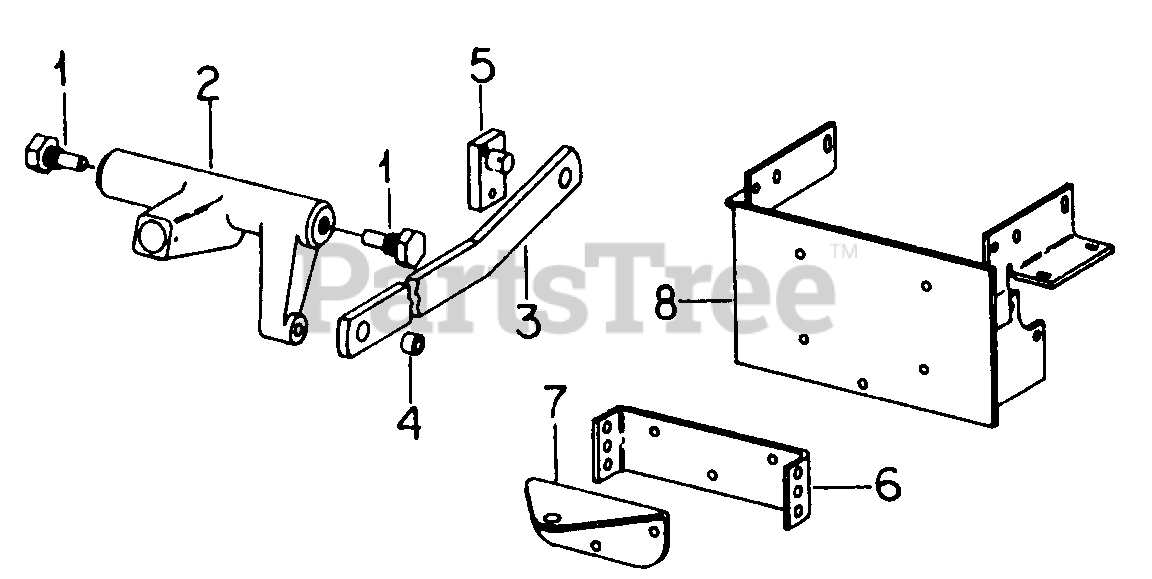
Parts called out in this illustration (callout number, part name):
1	Bolt, Stud Shaft
2	Lever, Lift
3	Bar, Lift
4	Spacer, Lift Arm
5	Plate Assy, Lift Bar
8	Bracket Assy, Hitch
